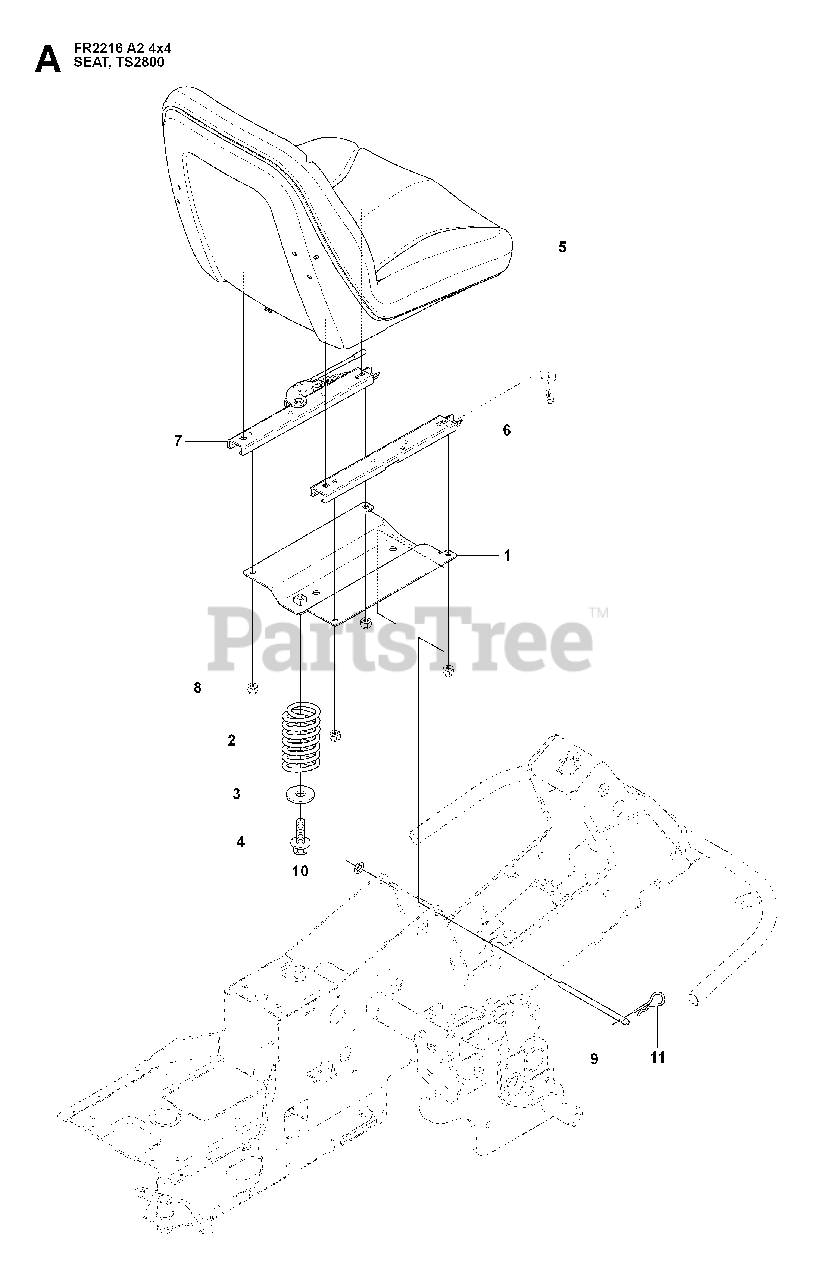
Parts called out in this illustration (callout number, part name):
2	SEAT SPRING
4	SCREW M10X25
8	LOCKNUT M8
10	RETAINING RING SGA 10
12	WASHER
13	BOLT
